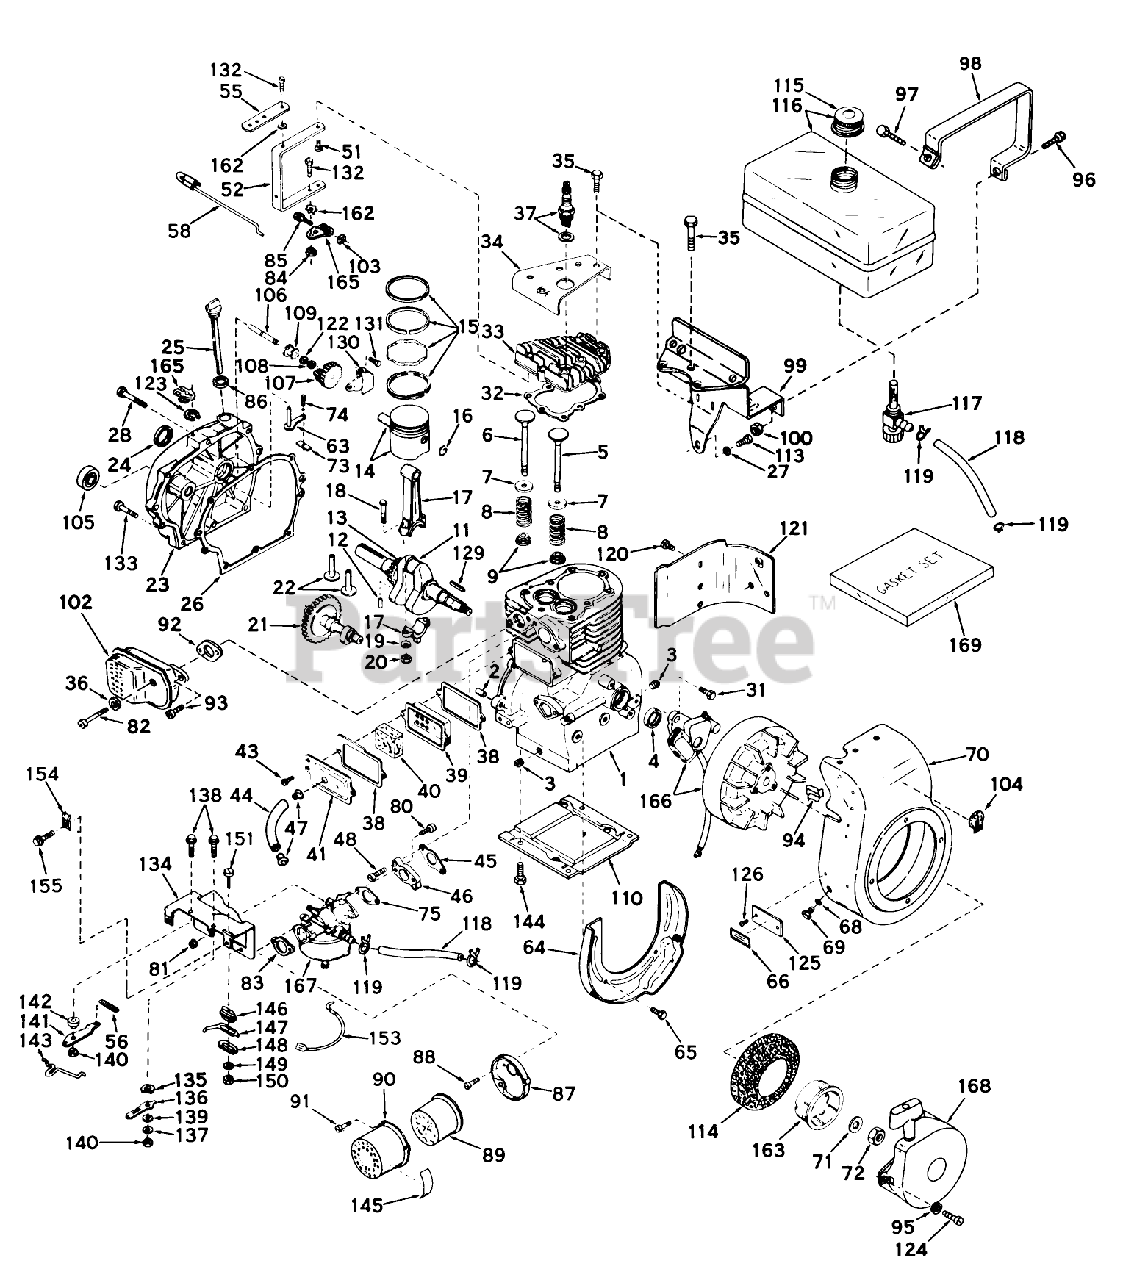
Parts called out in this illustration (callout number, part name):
1	Cylinder Assy. (Incl. Nos. 2, 3 4)
2	Pin-Dowel
3	Plug-Drain, Oil (SQH 1/4-18)
4	Seal, Oil
5	Valve, Intake (Std.)(Incl. No. 9)
5	Valve, Intake (1 /32" oversize)(Incl. No. 9)
6	Valve, Exhaust (Standard)(Incl. No. 9)
6	Valve, Exhaust (1/32" oversize)(Incl. No. 9)
7	Cap-Spring, Valve
8	Spring-Valve
9	Keeper-Spring, Valve
11	Crankshaft Assy. (Incl. Nos. 12 13)
12	Pin, Groove
13	Gear-Crankshaft
14	Piston Pin Assy., Std., (Incl. 2 of No. 16)
14	Piston Pin Assy., .010 oversize (Incl. 2 of No. 16)
14	Piston Pin Assy., .020 oversize (Incl. 2 of No. 16)
15	Ring Set (Standard)
15	Ring Set (.010 Oversize)
15	Ring Set (.020 Oversize)
17	Rod As sy. (Incl. Nos. 18, 19 20)
18	Bolt, Connecting Rod
19	Washer
21	Camshaft
22	Lifter Valve
23	Cover Cylinder (Incl. Nos. 24, 105 106)
24	Oil Seal
25	Dipstick, Oil (Incl. No. 30)
26	Gasket-Cover, Cylinder
27	Lockwasher
28	Screw (1/4-20 x 1-1/4)
31	Screw
32	Gasket-Head, Cylinder
33	CYLINDER HEAD
34	Cover, Cylinder head
35	Screw
36	Washer
37	SPARK PLUG
38	Gasket-Breather
39	Body-Breather
40	Element-Breather
41	Cover-Valve
43	Screw
44	Breather Tube
45	Gasket-Intake
46	Flange, Carburetor (Incl. Nos. 77 80)
47	GROMMET
48	Screw
51	Rivet, Split
52	Lever, Governor
56	Spring, Extension
58	Link, Governor to Throttle
63	ROD ASSY, Governor
64	Baffle Blower Housing
65	Screw (1/4-20x19/32)
66	Decal, Instruction
68	Lockwasher
69	Screw
70	Housing, Blower
71	Washer
73	Yoke-Governor
74	Screw (6-40x5/16)
75	Gasket-Carburetor
80	Screw
81	Nut and Lock Washer (1/4-28)
82	Screw
83	Gasket
84	Nut-Lock
85	Screw
86	Gasket
87	BRACKET, AIRCLEANER
88	Screw (10-32 x 1/2)
89	AIRCLEANER
90	Body
91	Screw
92	Gasket Exhaust
93	Screw
94	51004 GIL ROTARY TI
95	Washer
97	Screw
98	Strap, Fuel Tank
99	BRACKET, FUEL TANK
100	Nut and Lock Washer (1/4-28)
102	Muffler
103	Nut-Lock
104	Decal, Name H.P.
105	Seal, Oil
106	Shaft-Governor
107	Governor Gear ASM
108	Ring-Retaining
109	Spool-Governor
110	Base Engine
113	Screw
114	Screen, Air
116	Tank, Fuel (Incl. No. 115)
117	Fitting Shut-off, Fuel
118	Line-Fuel
119	Clamp-Line, Fuel
120	Screw
121	Emnsion, Blower Housing
122	Washer-Flat
123	Ring-Retaining
124	Screw
125	IDENTIFICATION PLATE
126	DRIVE STUD
129	Key, Flywheel
130	Bracket, Governor
131	Screw (10-32 x 35/64)
132	Screw
133	Screw
134	Bracket, Speed Control
135	Washer
136	Lever, Speed control
137	Washer, Flat
138	SCREW, HEX WASHER HD.
139	Bushing Control Lever
140	Nut
141	Lever, Bellcrank
142	Bushing
143	Link, RPM
144	Screw
145	DECAL, AIRCLEANER
146	Washer, Insulating
147	Terminal
148	Washer, Insulating
149	Washer, Flat
151	Screw, Hex Slotted Hd.
153	Wire, Ground
154	Conduit
155	Screw (10-32 x 3/8)
162	Washer-Lock
163	Cup-Starter
165	Clamp-Lever, Governor
166	Magneto
167	Carburetor
168	Starter, Rewind
169	Gasket Set
